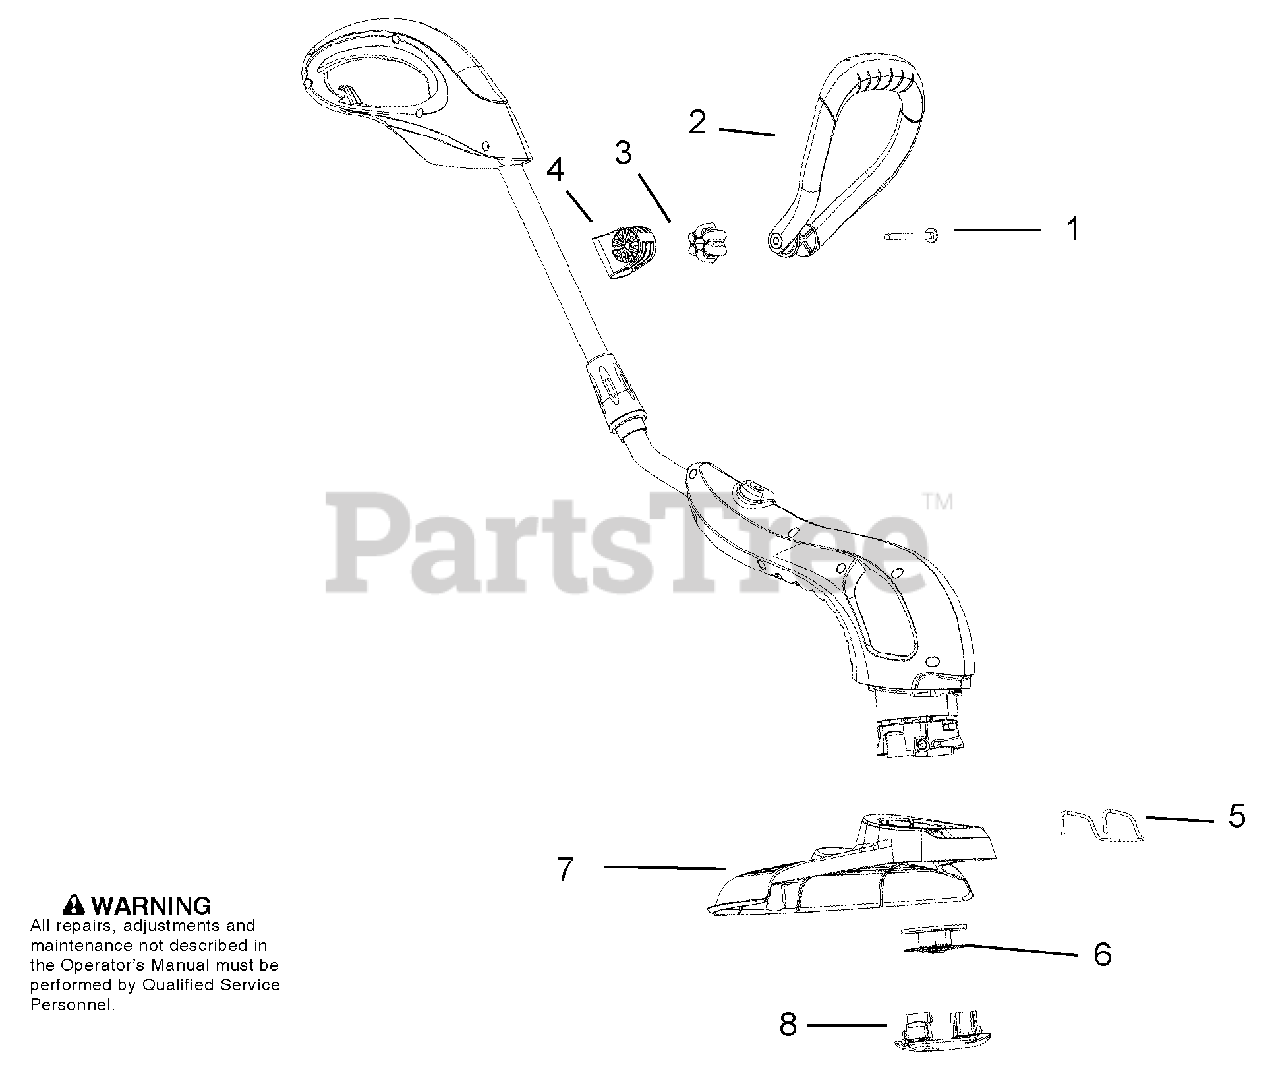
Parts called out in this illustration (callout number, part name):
1	Bolt Carriage, M6 X 1
2	Assit Handle
5	Edge Guide
6	Spool with 0.065 Trimmer line
7	Shield Assembly
8	Spool Cap
